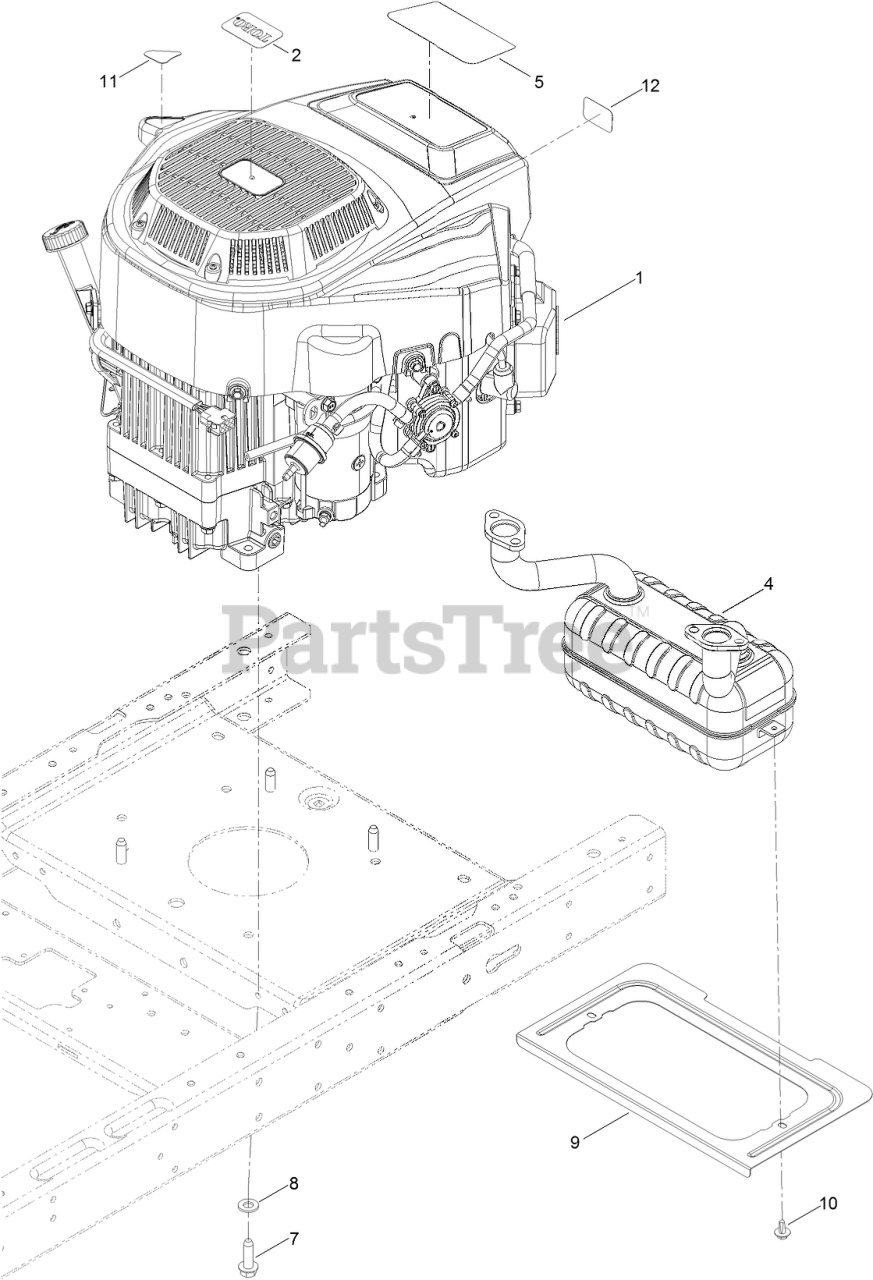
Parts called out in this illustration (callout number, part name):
1	ENGINE-2P77F
4	MUFFLER
5	DECAL-ENGINE
7	SCREW-TAPTITE
8	WASHER-FLAT
9	SHIELD-HEAT
10	SCREW-HHFTF
11	DECAL-DRAIN, OIL
12	PLACARD-INTAKE
